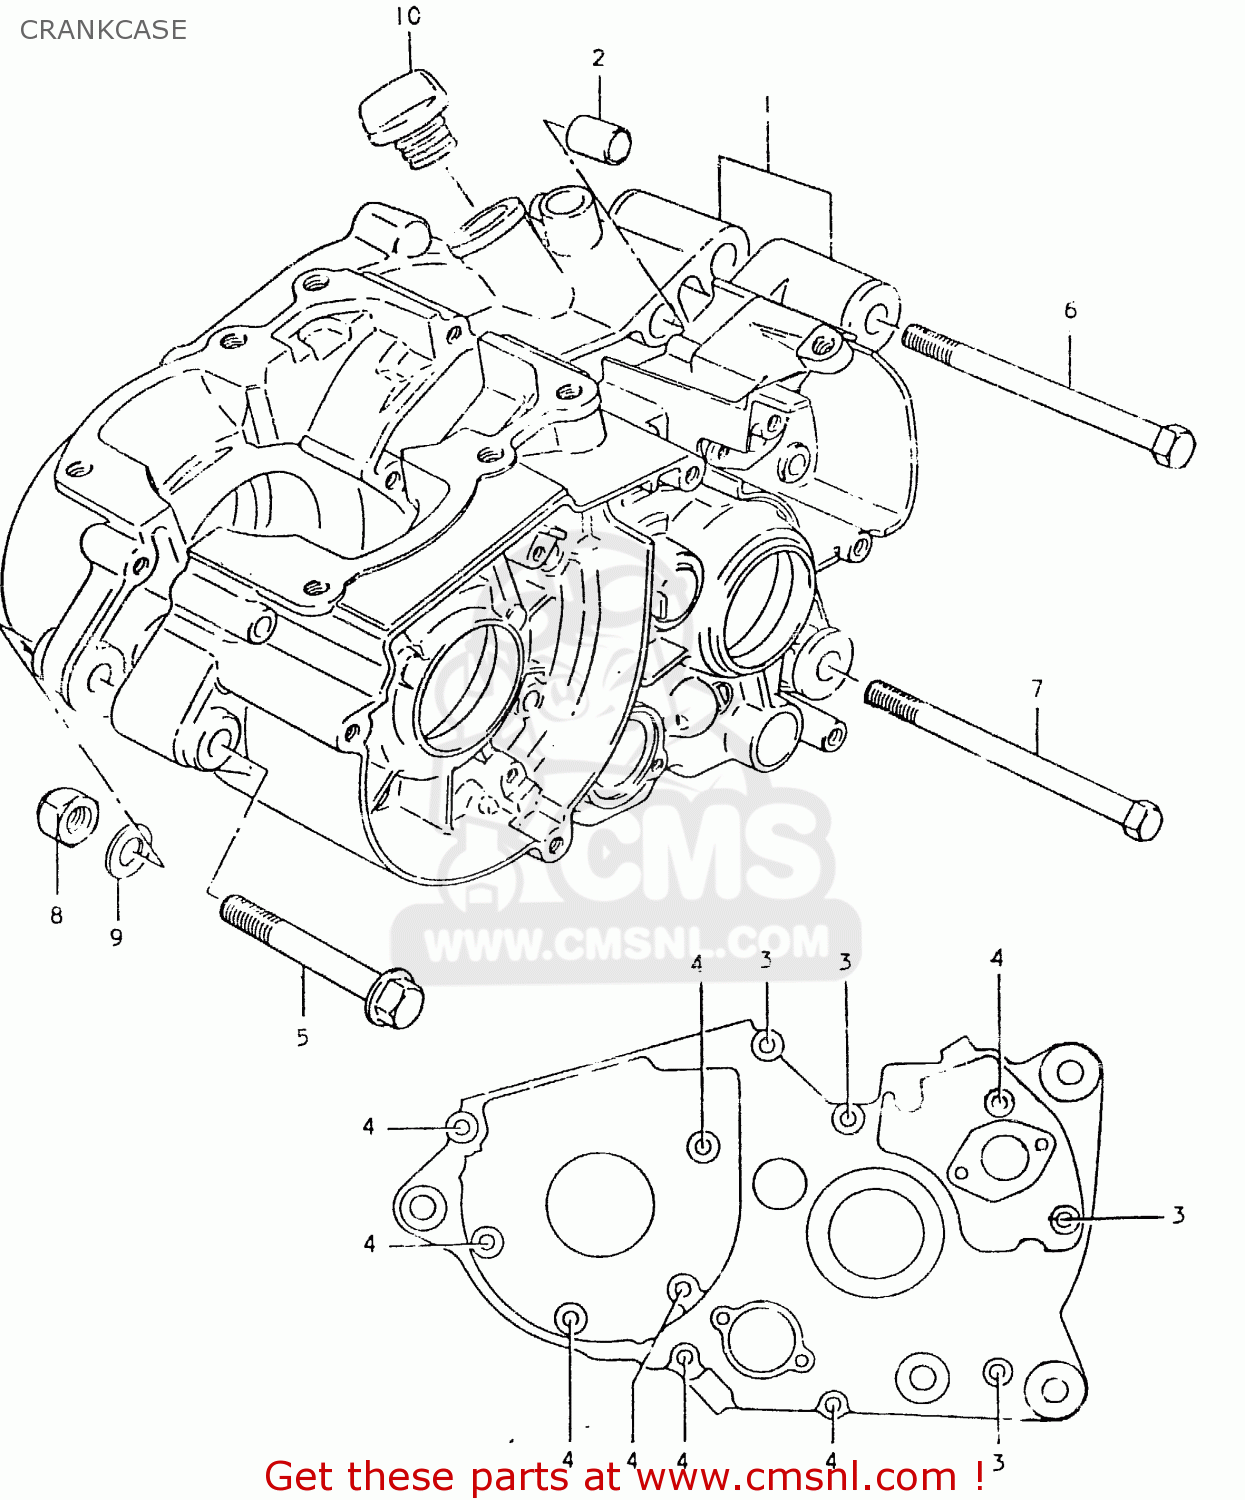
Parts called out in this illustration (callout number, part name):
1	CRANKCASE ASSEMBLY
2	PIN
3	SCREW
4	SCREW 6X60
5	BOLT (10X75)
6	BOLT(10X110)
7	BOLT
8	NUT
9	WASHER
10	PLUG
